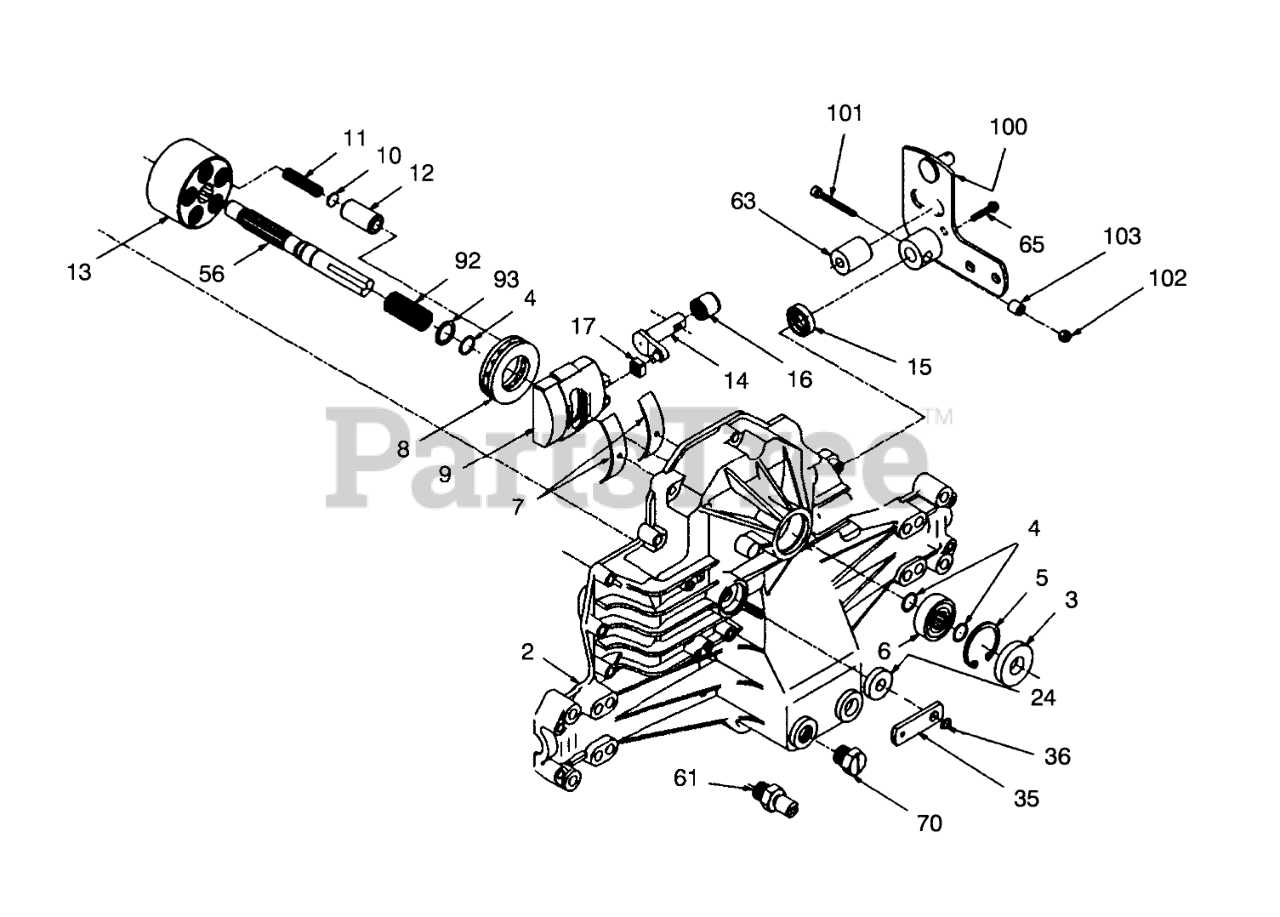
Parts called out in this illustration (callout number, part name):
2	Housing-Upper
3	SEAL-LIP
4	Ring-Wire Retaining
6	Bearing-Shaft Ball
7	Bearing-Cradle
9	Swashplate-Variable
10	Washer-Piston Thrust
11	Spring-Piston
13	Block Cylinder (Motor)
14	Arm-Trunnion
15	SEAL-LIP
16	Bearing-Trunnion Journal
17	Guide-Slot
24	SEAL-LIP
26	Plate-Bypass
35	ARM - BYPASS
36	RING-RETAINING
61	BREATHER ASSEMBLY
65	Bolt
70	Plug-Plastic
92	Spring-Block
93	Washer-Block Thrust
100	SPEED CNTRL LEVER WA
101	SCREW-HSH
102	NUT-LOCK, NI
103	LOCK SPACER
